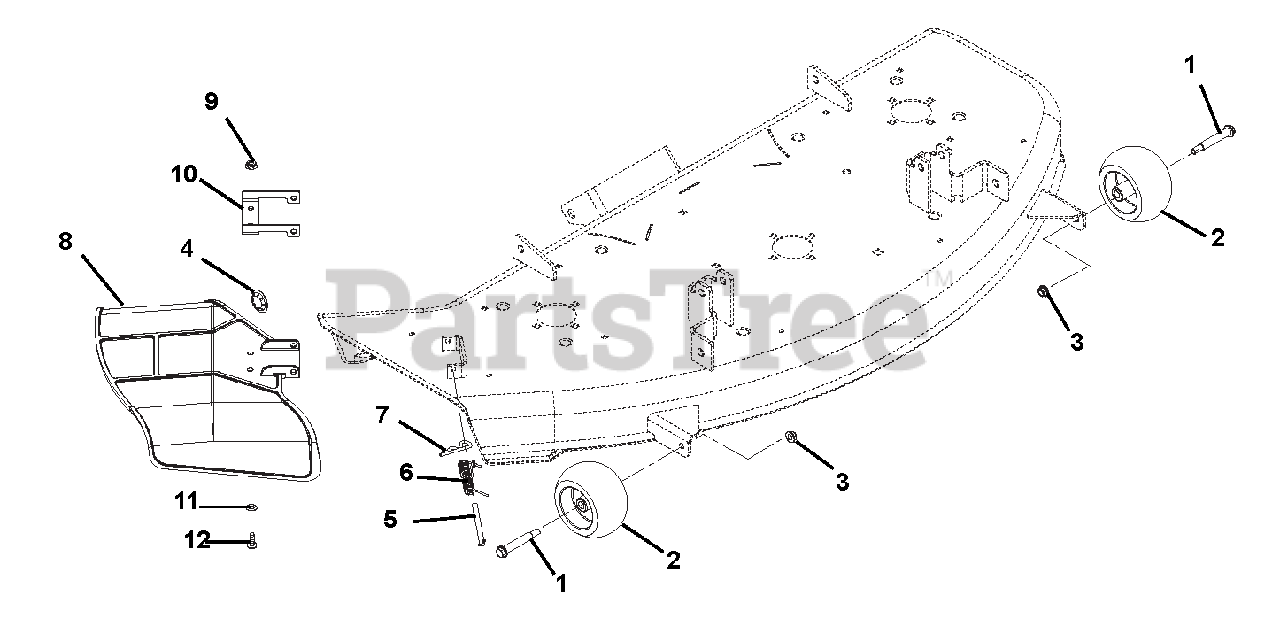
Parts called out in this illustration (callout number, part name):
1	BLT-SHLDR .38-16X2.50 HWH G5
2	WHEEL 5 X 3
3	@NUT-LK-TOP-FLG .38-16 YWZC
4	PUSH NUT, .625 SHAFT
5	PIN, 5/16 X 3.88"
6	SPRING, TORSION
7	PIN-HAIR INT .08X.18X1.18 YWZC
8	MOLDED CHUTE, ZOOM
9	@NUT-LK-TOP-FLG .31-18 YWZC
10	CHUTE REINFORCEMENT
11	@WSHR-FL-STL.38X.875X.083 YWZC
12	SCR-SKH .31-18X.75 BTNHD YWZC
